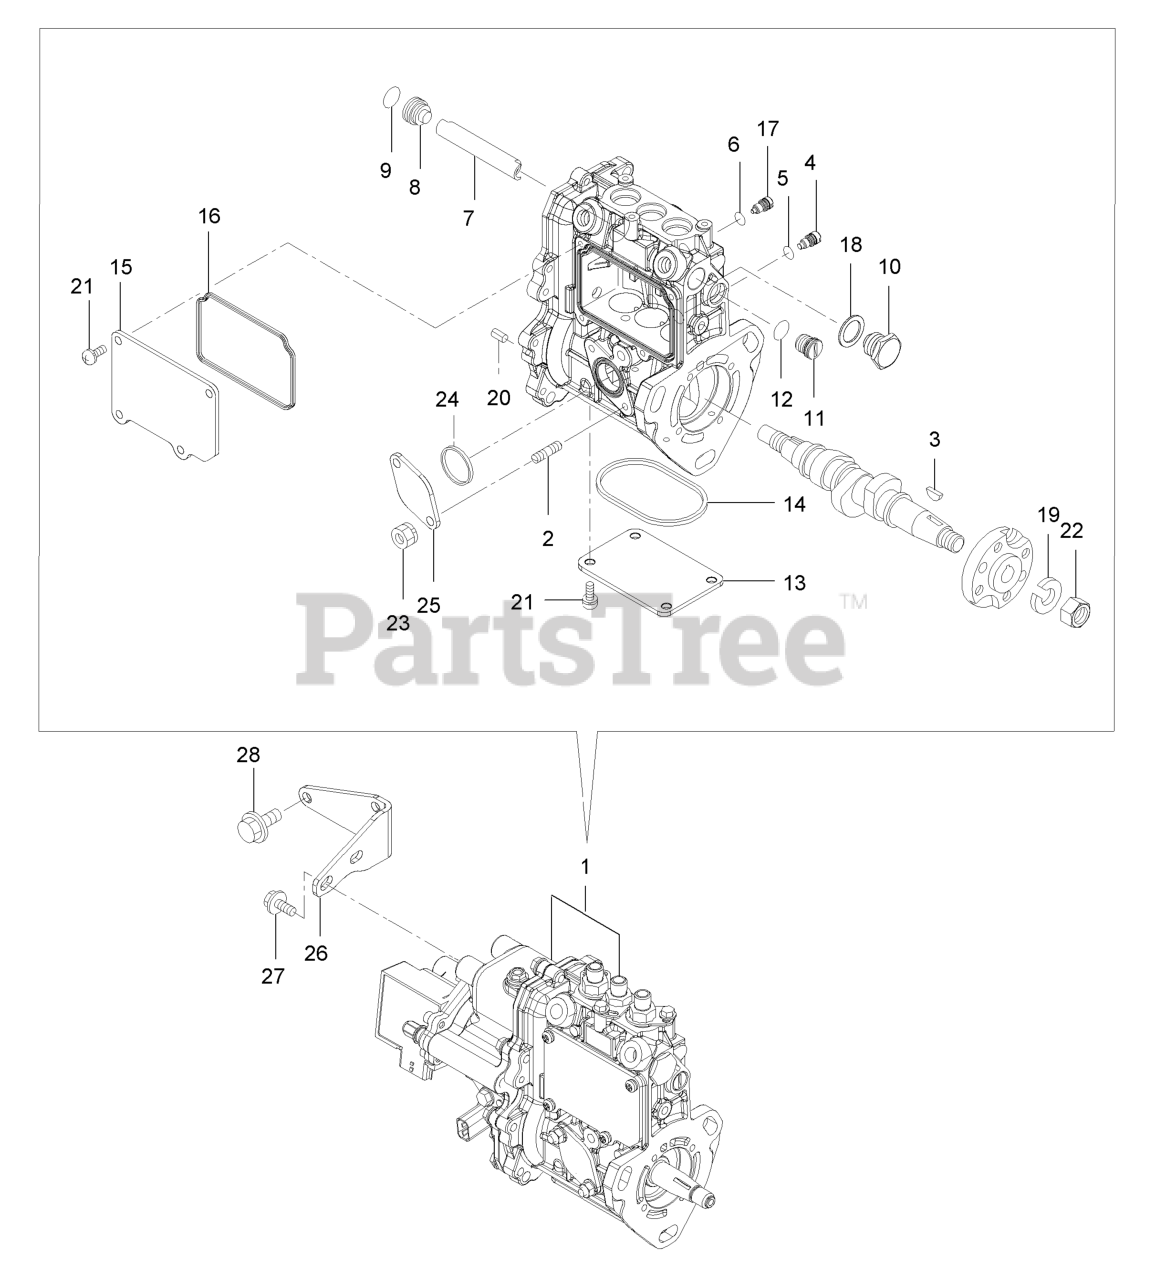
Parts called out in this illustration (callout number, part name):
1	Fie ASM
2	Bolt-Stud
3	Feather Key-Woodruff
4	Stopper
7	Deflector
8	Plug-Deflector
10	Plug-Deflector
11	Plug-Rack
17	Stopper-Rack
18	Washer-Seal
19	Washer-Spring
20	Pin-Spring
25	Cover-Pump
26	Support
